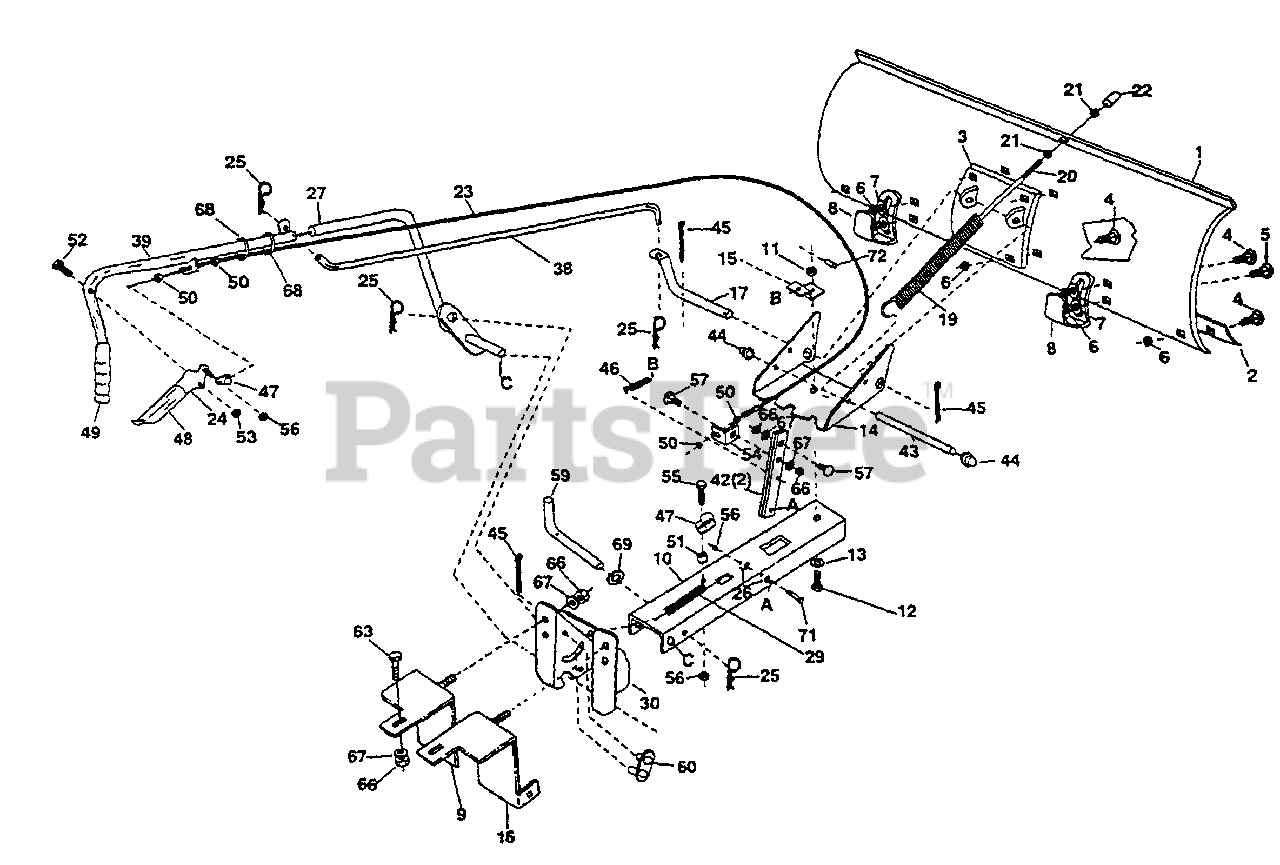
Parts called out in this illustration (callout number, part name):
1	Blade 42"
2	Wear Plate 42"
3	Reinforcement Plate Ass'y.
4	Bolt, Carriage 5/16-18 x 3/4"
5	Bolt, Carriage 5/16-18 x 1"
6	Nut, Hex Lock 5/16-18
7	Washer, 5/16"
8	Skid Shoe
9	Support Bracket (L.H.)
10	Ass'y. Channel Sub
11	Nut, Hex Lock 1/2-13
12	Bolt, Special Pivot
13	Washer, Flat 7/16"
14	Plate, Pivot 7 Ga.
15	Bracket, Spring Mt.
16	Support Bracket (R.H.)
17	Shaft Pivot
19	Spring, Blade Adjust
20	Bolt, Hex 3/8-16 x 3-1/2"
21	Nut, Hex 3/8-16
22	Plastic Cap
23	Control Cable Ass'y.
24	Release Grip Ass'y.
25	Pin, Hairpin Small 3/32"
26	Spacer, .28 I.D. x 1"
27	Lift Handle Rod Ass'y.
29	Extension Spring
30	Pivot Support Bracket
38	Rod, Blade Pivot
39	Ass'y. Lift Handle Tube
42	Angle Lock Bar
43	Spring Mount Rod
44	Palnut, 3/8"
45	Cotter Pin 1/8" x 1-1/4"
46	Angle Lock Spring
47	Cable End Fitting
48	Grip, Plastic
49	Handle, Grip 3/4"
50	Hex Jam Nut 5/16 Thread
51	Spacer
52	Hex Bolt, 5/16-18 x 1-1/2"
53	Hex Lock Nut 5/16-18 Thread
54	Cable Mount Bracket
55	Hex Bolt 1/4-20 x 1-1/4"
56	Hex Lock Nut 1/4-20 Thread
57	Carriage Bolt 3/8-16 x 1-1/4"
59	Pivot Channel Shaft
60	Lift Link Ass'y.
63	Hex Bolt 3/8-16 x 1"
66	Hex Nut 3/8-16 Thread
67	Lock Washer 3/8"
68	Plastic Tie
69	Washer
71	Bolt, Hex 1/4-20 x 3-1/4" Lg. (Gr. 5)
72	1/4" x 1" Spring Pin
